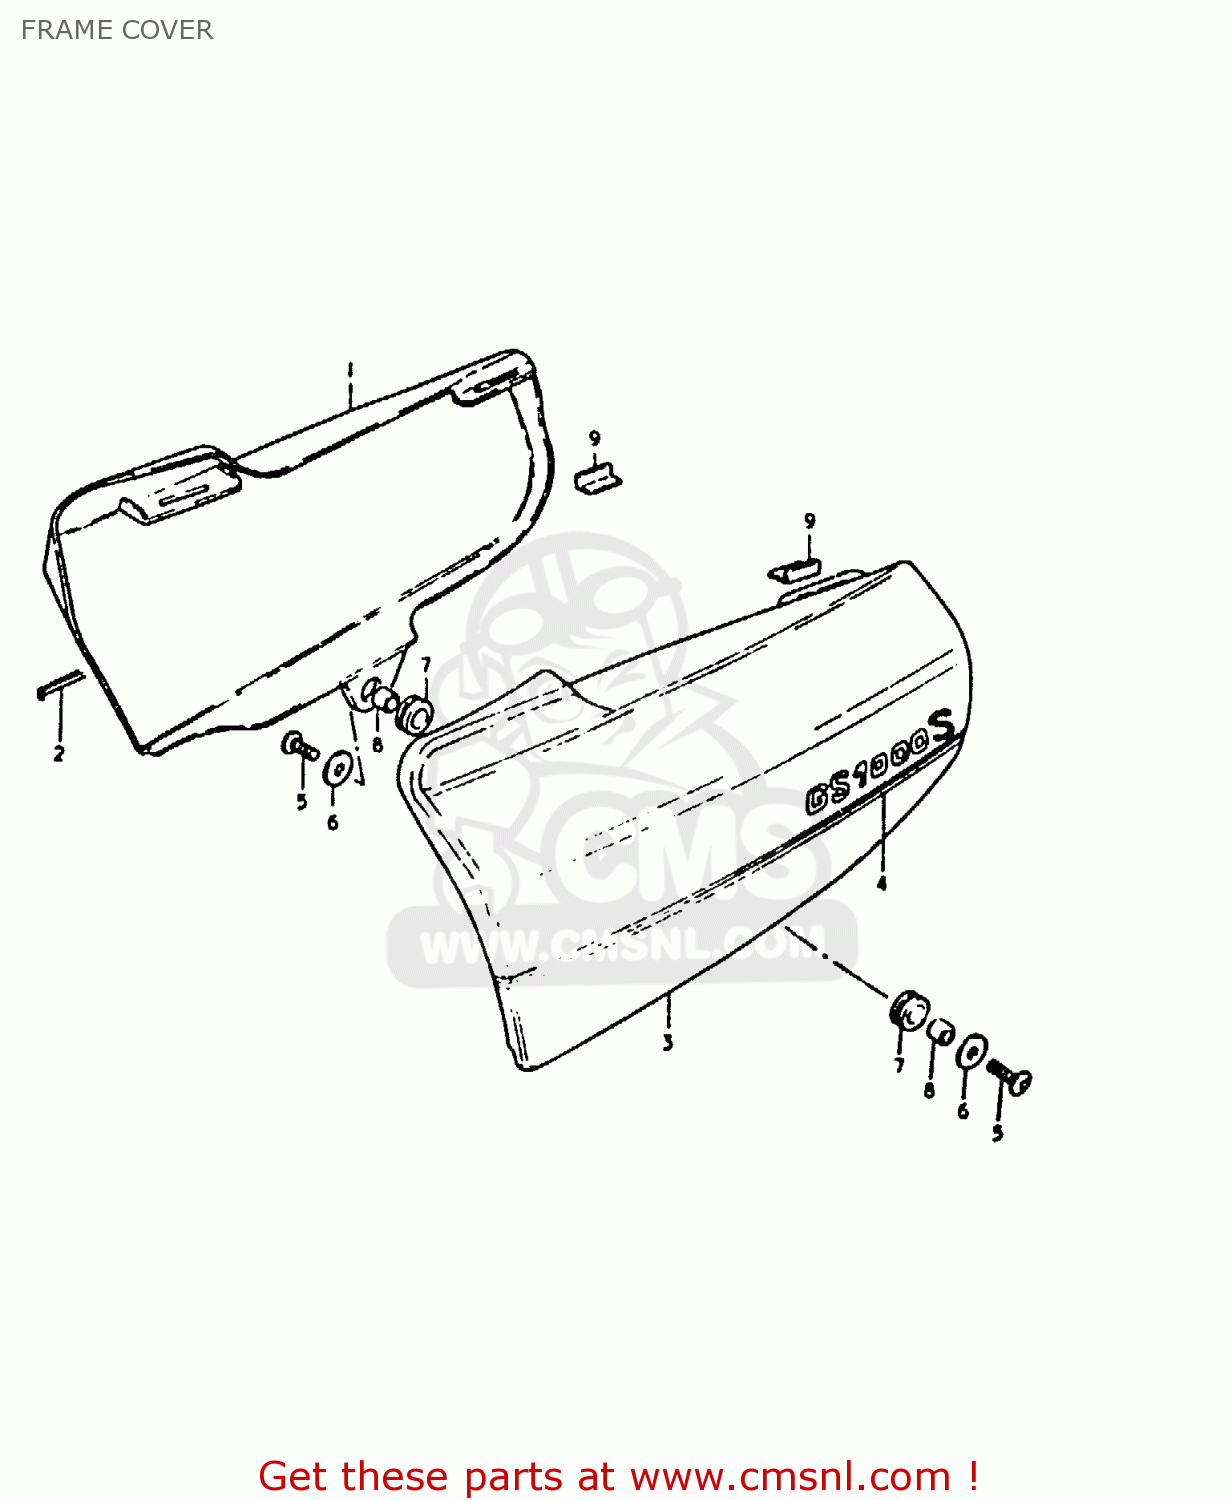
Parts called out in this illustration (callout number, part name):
1	COVER,FRAME,RIGHT
2	TAPE,FRAME COVER
3	COVER,FRAME,LEFT
4	TAPE,FRAME COVER
5	SCREW (6X20)
6	WASHER (6.5X18X1.6)
7	CUSHION
8	SPACER (6.8X10X10)
9	CUSHION,FRAME COVER
